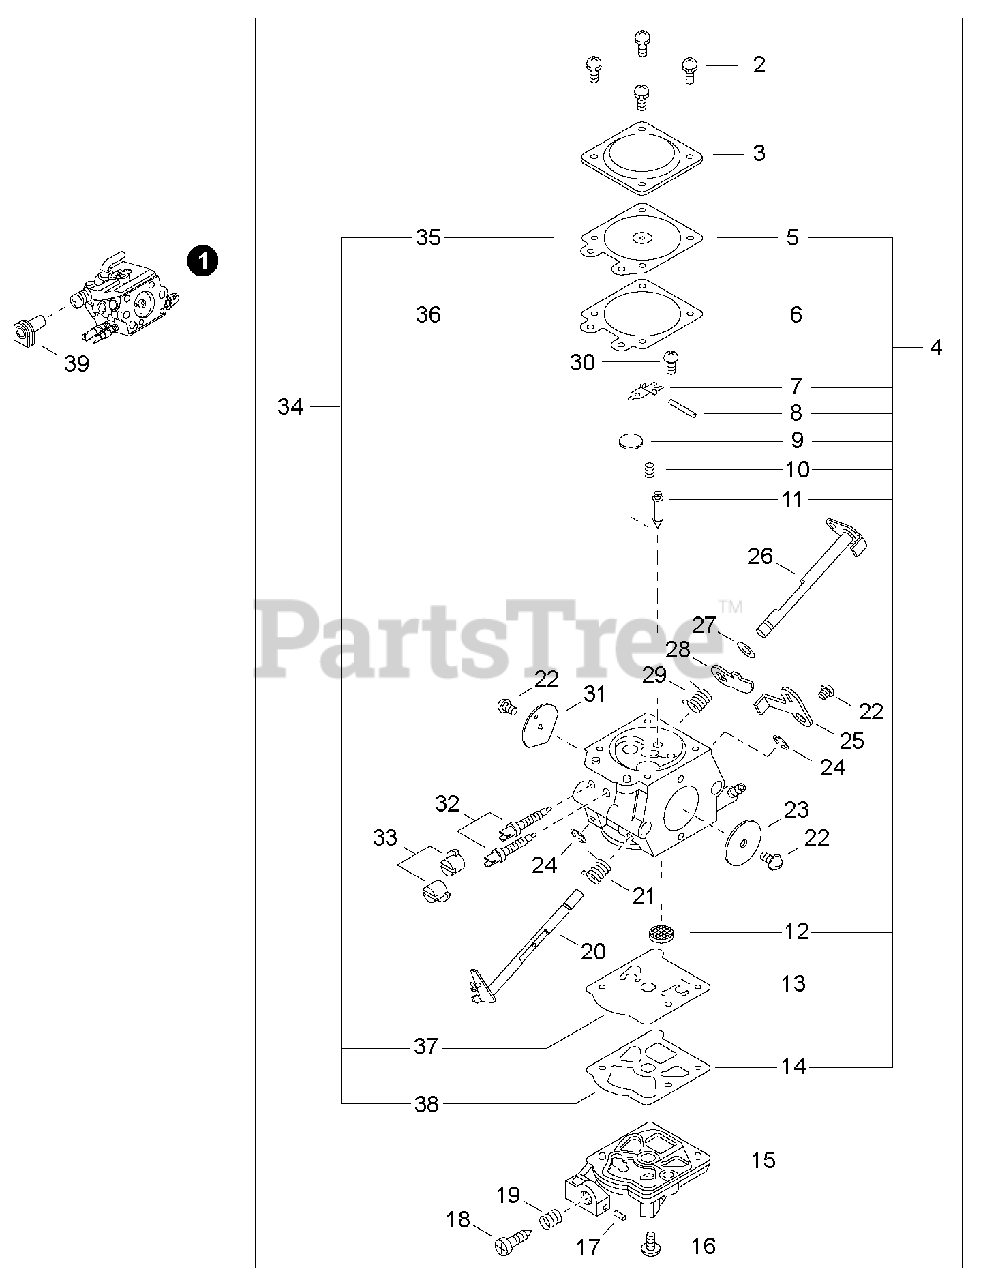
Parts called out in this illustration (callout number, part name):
1	CARBURETOR - WT-594
3	COVER, METERING DIAPHRAGM
4	REPAIR KIT, CARBURETOR
5	DIAPHRAGM, METERING
6	GASKET, METERING DIAPHRAGM
7	LEVER, METERING
8	PIN, METERING LEVER
9	PLUG, WELCH
10	SPRING, METERING LEVER
11	VALVE, INLET NEEDLE
12	SCREEN, FUEL INLET
13	DIAPHRAGM, PUMP
14	GASKET, FUEL PUMP
15	COVER, FUEL PUMP
17	PLUG, FRICTION
18	SCREW, IDLE ADJUST
19	SPRING, IDLE ADJUST
20	SHAFT, THROTTLE
21	SPRING, THROTTLE RETURN
23	VALVE, THROTTLE
25	LEVER, THROTTLE
26	SHAFT, CHOKE
28	LEVER, FAST IDLE
29	SPRING, CHOKE RETURN
30	SCREW, METERING LEVER PIN
31	VALVE, CHOKE
32	NEEDLE, MIXTURE
33	CAP, LIMITER
34	GASKET / DIAPHRAGM KIT
35	DIAPHRAGM, METERING
36	GASKET, METERING DIAPHRAGM
37	DIAPHRAGM, PUMP
38	GASKET, FUEL PUMP
39	GROMMET, IDLE
